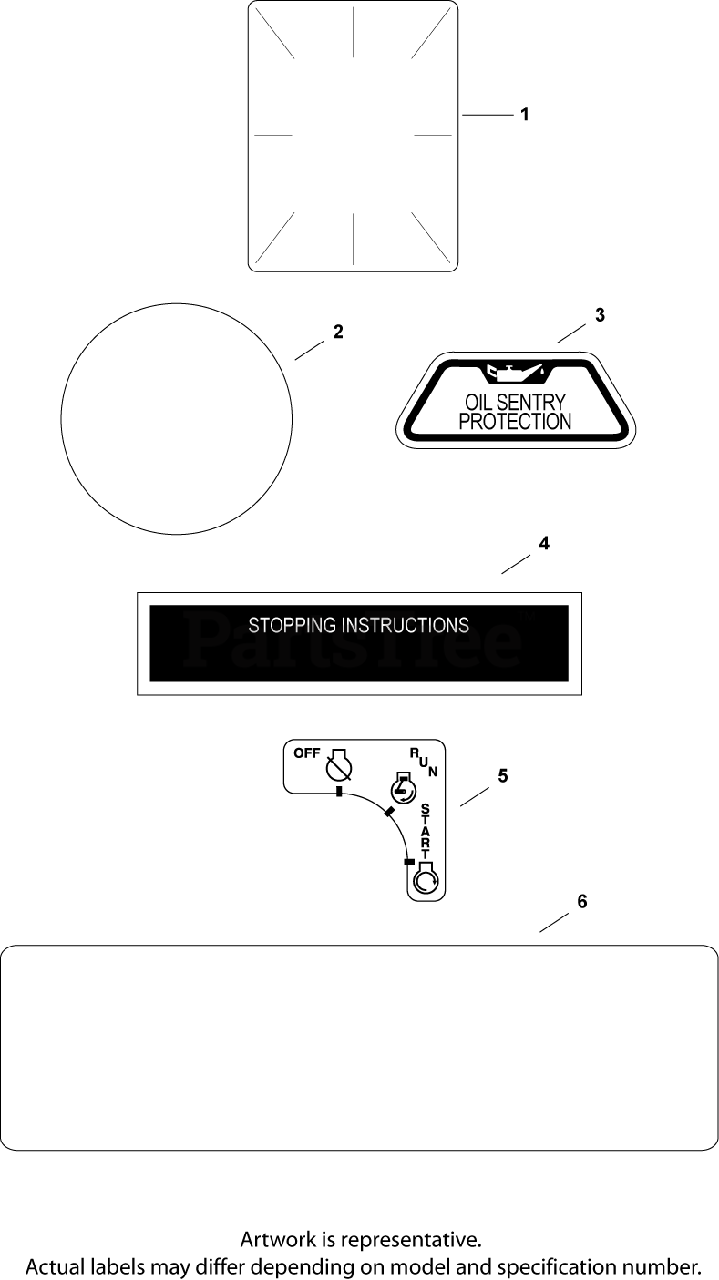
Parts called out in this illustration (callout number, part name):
1	DECAL, CLEAR LAMINATE USE 25 113 70-S
2	DECAL, GRASS SCREEN USE 24 113 499-S
3	DECAL, OIL SENTRY - (#DSC)
4	DECAL, STOPPING INSTRUCTION
5	DECAL, KEY SWITCH
6	DECAL, 25 HP - DISCONTINUED
